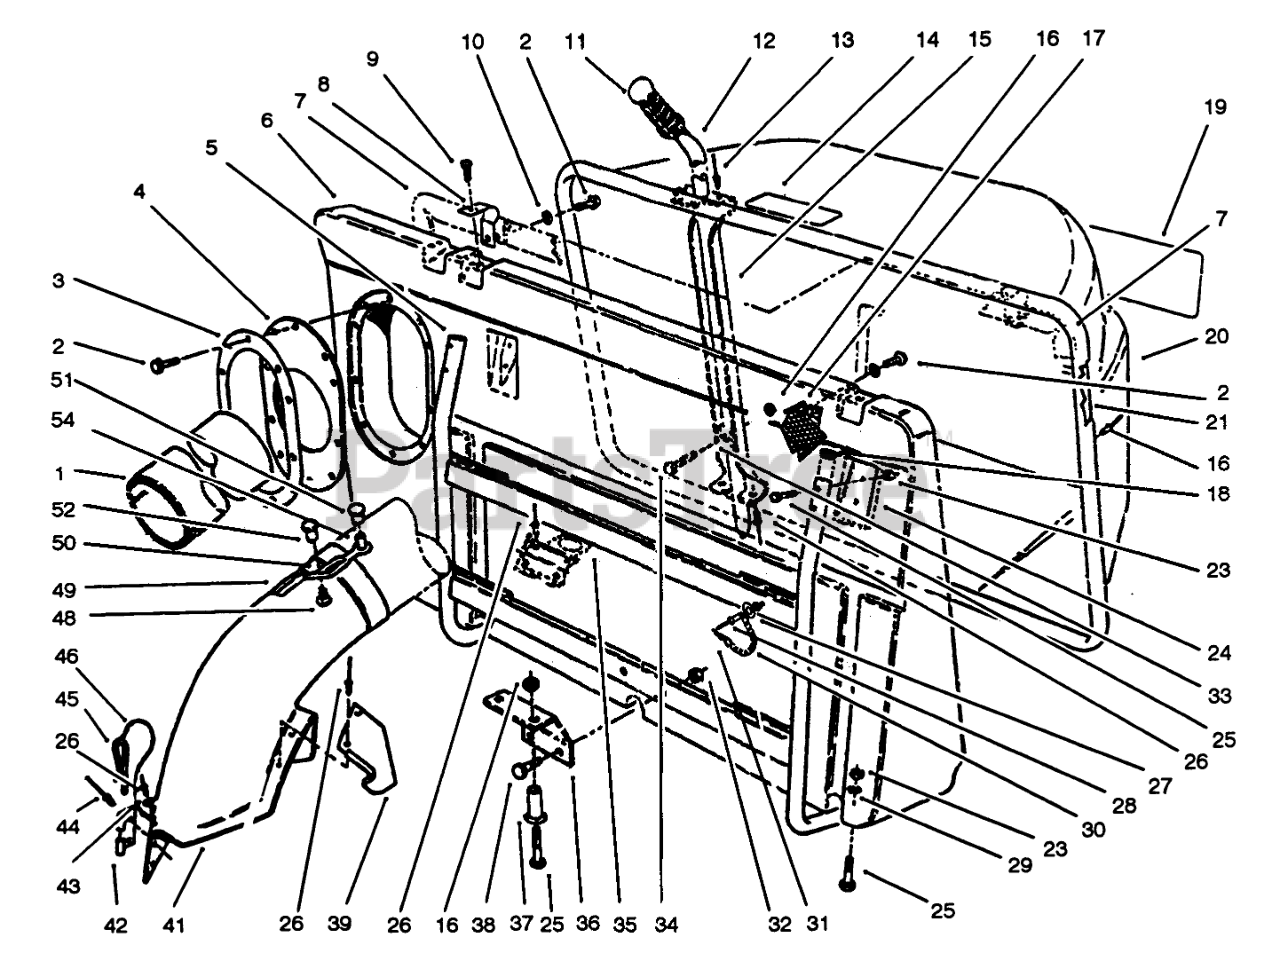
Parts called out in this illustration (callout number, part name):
2	SCREW-HWHTF
3	RING-RETAINING
4	RING-RETAINER, RUBBER
5	Frame
6	BAG-FRONT
7	SEAL-BAG
8	Bracket-Hinge
9	SCREW-HH
10	WASHER-FLAT
11	GRIP-HANDLE
12	HANDLE-DUMP
13	RIVET-POP
14	Decal Warning
15	Channel-Dump Handle
16	NUT-LOCK, NI
17	Screen Bag
19	DECAL - TORO
20	BASKET-GRASS
21	Frame-Grass Basket
23	NUT-LOCK, NI
24	Plate-Backup
25	SCREW-HH
26	RIVET-BLIND
27	WASHER
29	WASHER-FLAT
30	10 LINK CHAIN W/O HOOK
31	PIN-HAIR
32	NUT-LOCK, NI
33	GUIDE-HANDLE, DUMP
34	SCREW-HH
35	Latch
36	Bracket-Hitch
37	Spacer
38	SCREW-HH
39	CHUTE SUPT BRKT
41	Chute Ass-y. (Incl. Ref. #26, 39, 42-49 & 52)
42	BRACKET-MOUNTING, CHUTE
43	WASHER-PLAIN
44	RIVET-BLIND
45	PIN-LOCKING, CHUTE
46	LANYARD
48	Screw
49	DECAL-DANGER
50	RETAINER-DUCT
51	SPACER-INTERLOCK
54	FASTENER-PANEL
